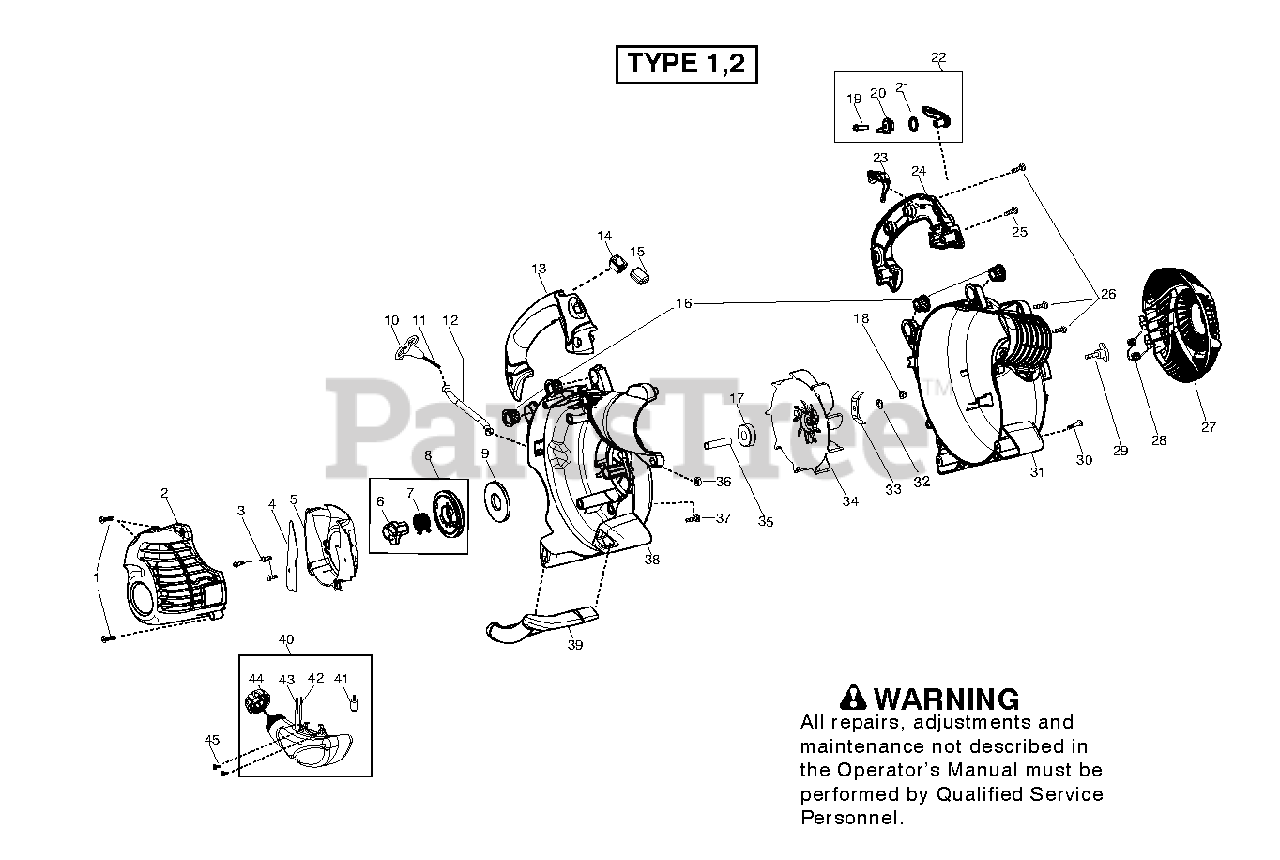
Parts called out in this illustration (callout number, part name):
2	ASSY COVER ENGINE S
4	SHIELD BAFFLE
6	Pulley Hub, Si Sm
8	KIT STARTER PULLEY
9	SPRING STARTER SA
11	Starter Rope Kit
12	TUBE STARTER ROPE
13	Handle with Soft Grip, RT
14	KIT SWITCH
15	PROTECTOR, SWITCH
20	RATCHET CRUISE CONTROL
22	TRIGGER THROTTLE CONTROL
25	SCREW #10 PLASTITE 1.362
27	DOOR VAC BLACK
28	SPRING VAC DOOR
31	ASSY SCROLL AV LH SRS BLK
34	ASSY IMPELLAR HUB
35	SPACER FLYWHEEL
38	ASSY SCROLL BEARING BLACK
40	Fuel Tank Assembly, Non Low Perm St
41	FUEL PICK-UP ASSY
44	ASSY FUEL CAP W/RETAINER
45	SCREW FUEL TANK RETAINER
